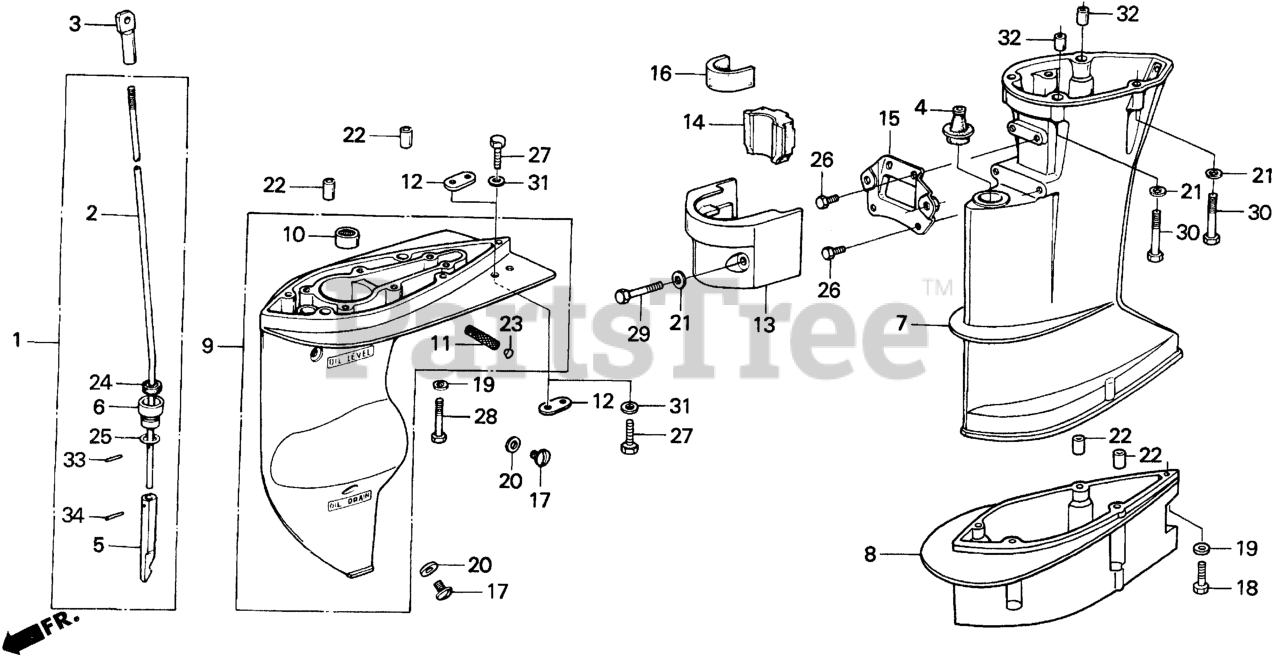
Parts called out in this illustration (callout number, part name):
1	ROD, GEARSHIFT (S)
2	ROD, GEARSHIFT (S)
3	JOINT, GEARSHIFT ROD
4	GROMMET, ROD (ARAI)
5	ROD, PUSH
6	HOLDER, SEAL
7	CASE, EXTENSION *B107* (S) (SENIOR BLUE)
9	CASE, GEAR *B107* (SENIOR BLUE)
10	BEARING, NEEDLE (15X21X16)
11	SCREEN, WATER
12	METAL, ANODE
13	HOUSING, SETTING (LOWER) *B107* (SENIOR BLUE) (NOT AVAILABLE)
14	RUBBER A, MOUNTING (LOWER)
15	PLATE, MOUNTING (LOWER)
16	RUBBER B, MOUNTING (LOWER)
17	BOLT, OIL CHECK
19	WASHER, PLAIN (6MM) Use from Frame SN 4800713.
20	WASHER, NYLON (8MM)
21	BOLT, FLANGE (6X35) (NOT AVAILABLE)
21	WASHER, PLAIN (8MM) Use from Frame SN 4800713.
22	PIN, DOWEL (8X10) Use up to Engine SN 2056819.
22	BOLT, STRAIGHT SLOT (4X6)
23	WASHER, PLAIN (6MM) Use from Frame SN 4800713.
23	PLUG, SEALING (10MM)
24	PIN, SPLIT
24	PIN, SPLIT (2.0)
24	SEAL, WATER (6MM)
25	O-RING (13.8X2.5)
25	CLIP B, CORD
26	BOLT, HEX. (6X12)
26	BOLT, HEX. (6X8)
27	BOLT, HEX. (6X16)
28	BOLT, HEX. (6X40)
29	BOLT, HEX. (8X40)
30	BOLT, HEX. (8X50)
31	WASHER, PLAIN (6MM)
32	PIN A, DOWEL (10X14)
33	PIN, SPRING (2.5X12)
34	ROLLER (2.5X11.8)
